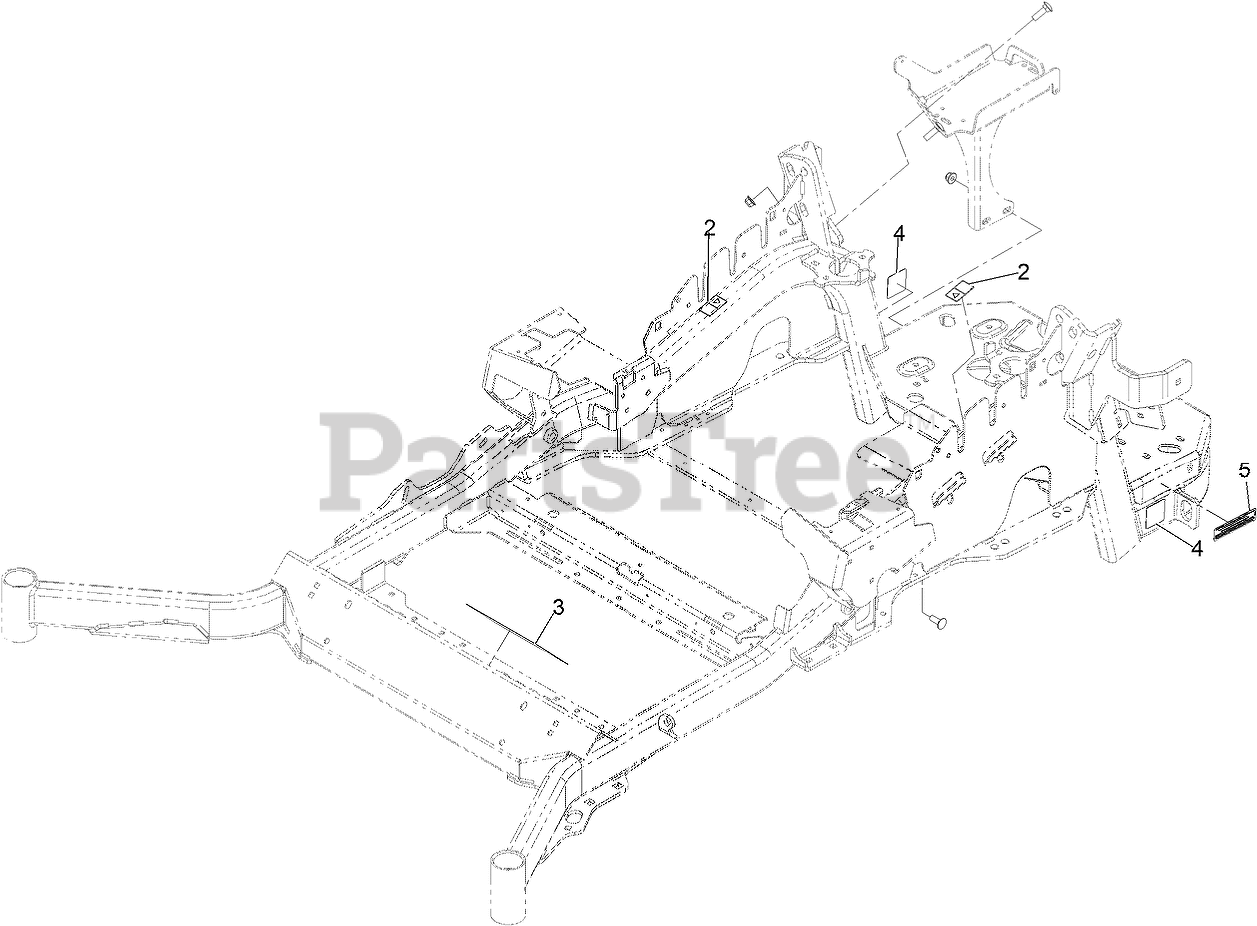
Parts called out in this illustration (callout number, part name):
2	DECAL-WARNING
3	DECAL-DANGER
4	DECAL-HAZARD, PINCHED FINGER
5	DECAL-ARRESTOR, SPARK
